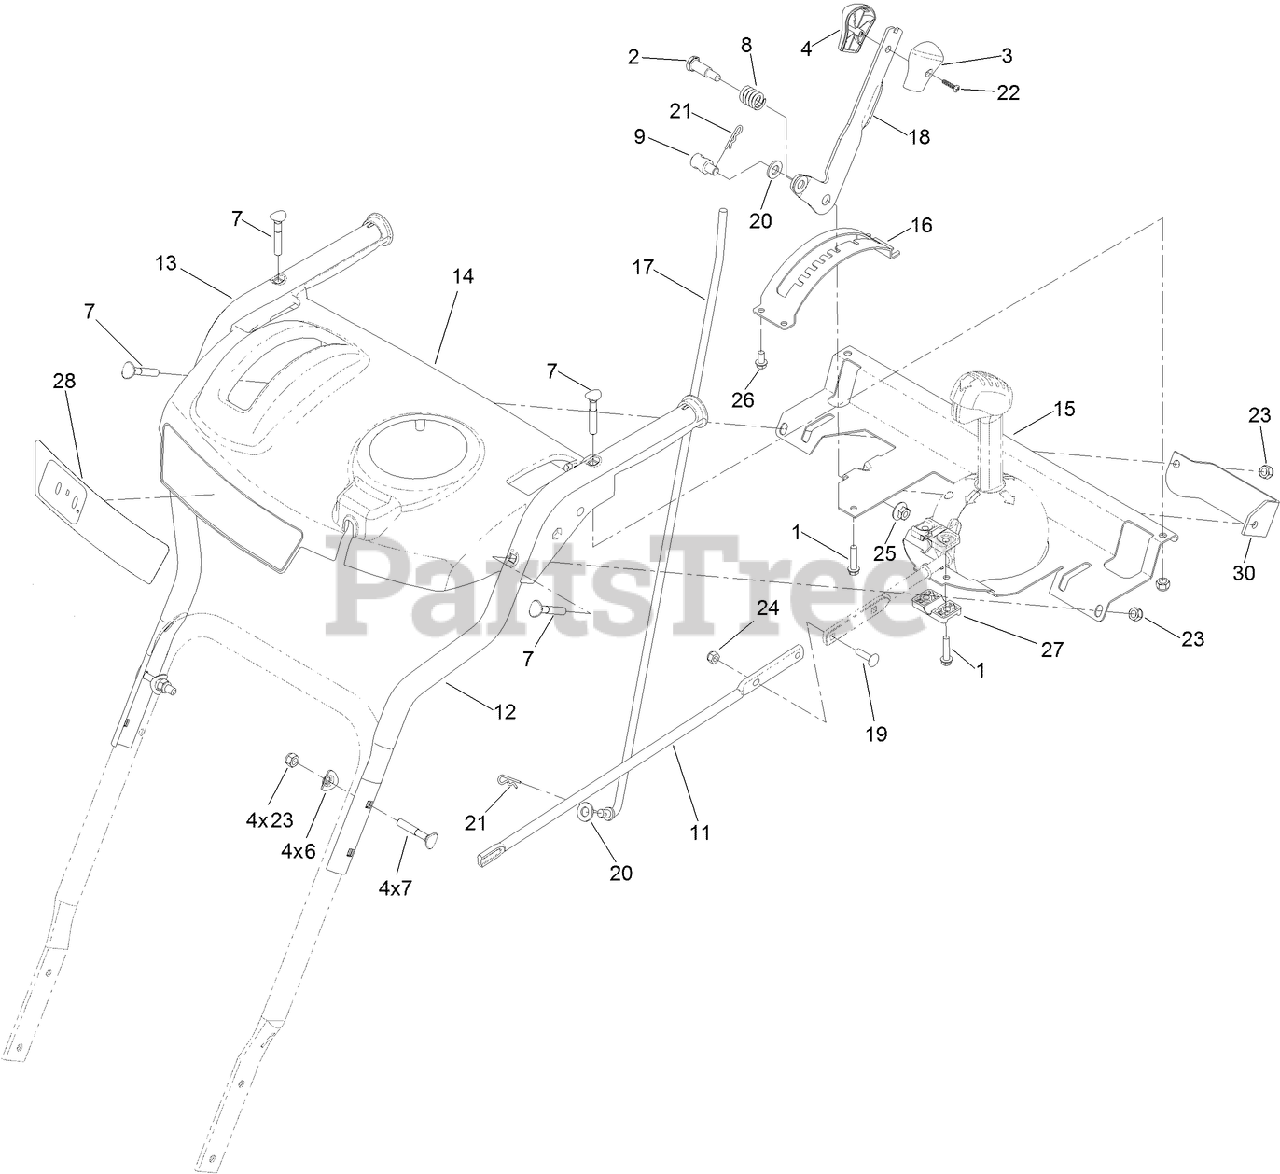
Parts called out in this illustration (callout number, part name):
1	SCREW-PLASTITE
2	SCREW-SHOULDER
3	KNOB-SHIFT, LH
4	KNOB-SHIFT, RH
6	WASHER
7	SCREW-HANDLE
9	TRUNNION-ROD
11	ROD-CHUTE, FRONT
12	HANDLE-UPPER, LH
13	HANDLE-UPPER, RH
14	PANEL-CONTROL, MASTER
15	SUPPORT-PANEL, CONTROL
16	MOUNT-SELECTOR, SPEED
17	ROD-SELECTOR, GEAR
18	SELECTOR-SPEED
19	SCREW-CARR
20	WASHER-FLAT
22	SCREW-PPH
23	NUT-LOCK, NI
24	NUT-LOCK, NI
25	NUT-HF
26	SCREW-PLASTITE
27	SUPPORT-ROD
28	DECAL-MODEL
30	PLATE-SUPPORT, SHIFT
